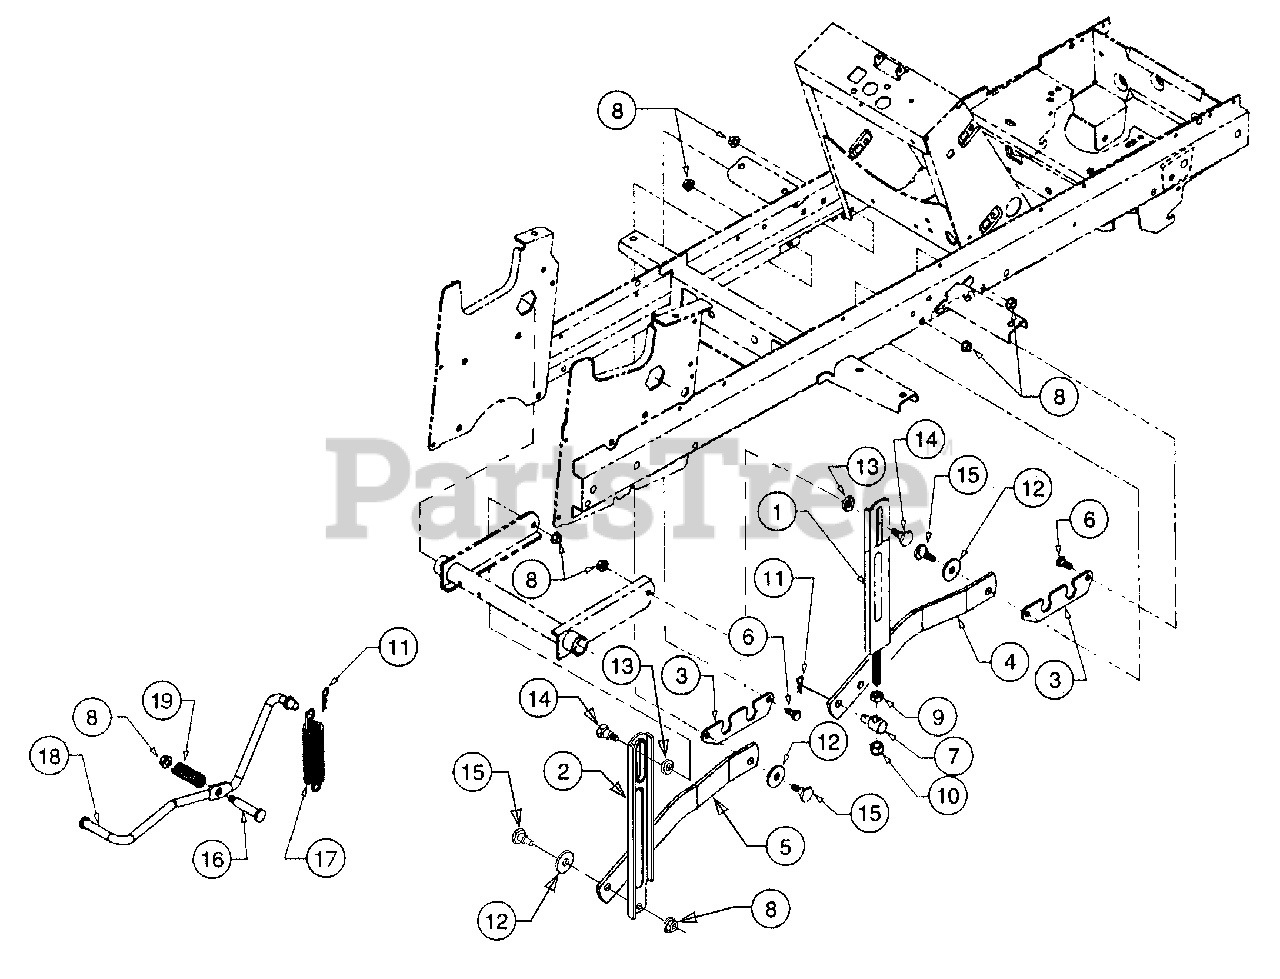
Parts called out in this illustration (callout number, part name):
7	Ferrule, Adjustment
8	Nut, Hex Flange Lock, 3/8-16
9	Nut, Hex Jam, 1/2-13 GR5
10	Nut, Hex Insert Lock, 1/2-13
11	Pin, Internal Cotter
12	Washer, Flat, .5 x 1.5 x .15
13	Washer, Flat, .531 x .875 x .15
14	Bolt, Shoulder
15	Bolt, Shoulder
16	Bolt, Shoulder
17	Spring, Ext., .91" OD x 7.33
18	Rod, RH Lift Assist
19	Spring, Compression, .63 ID x 2
